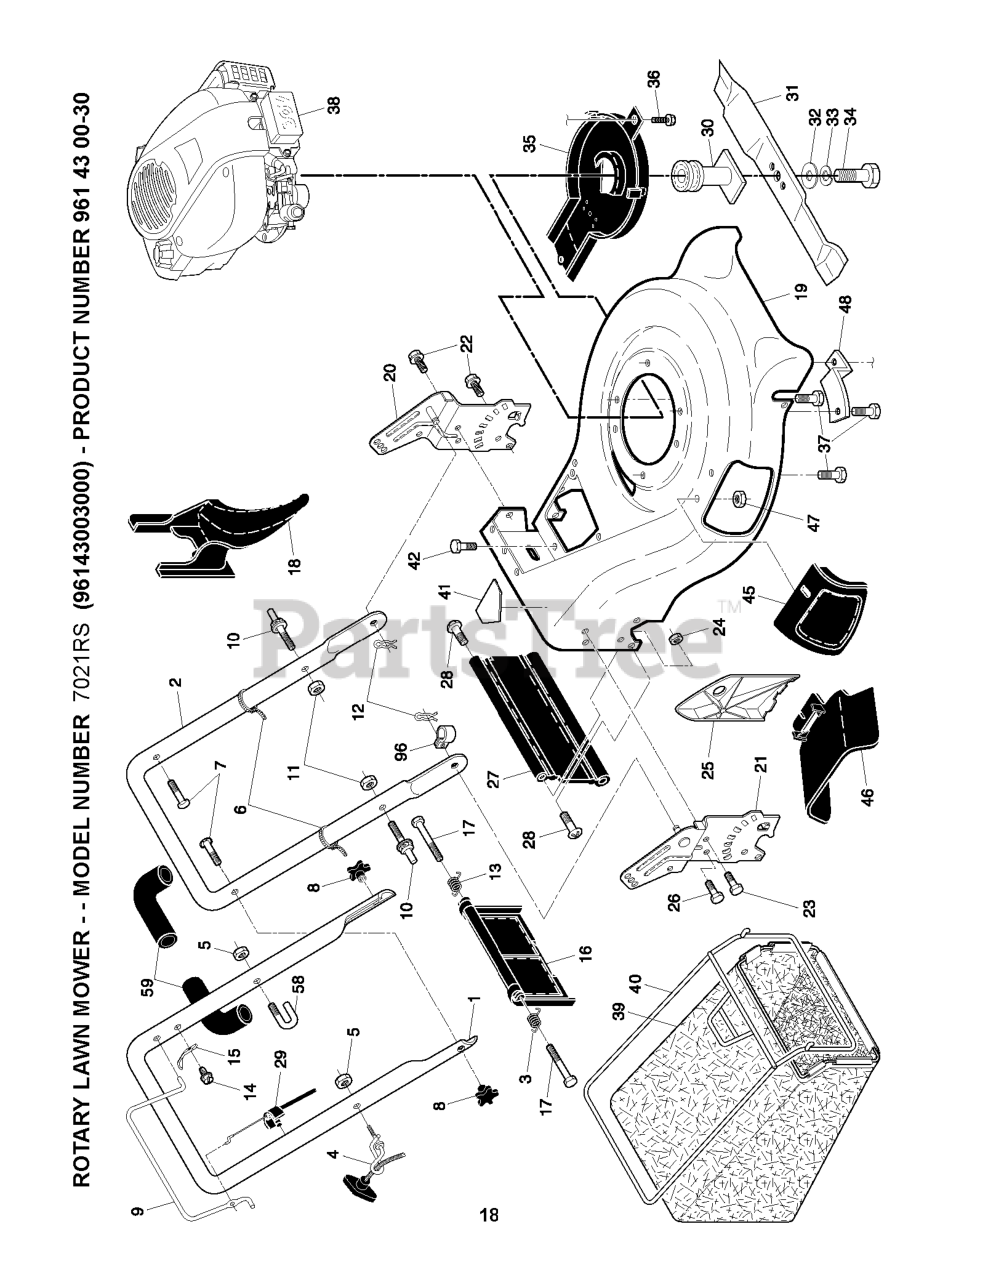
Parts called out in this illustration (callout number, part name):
1	HANDLE.ASM.UP.OFF/EZ.CR.W/GRIP
2	HANDLE.LOWER.21.GREY
3	SPRING.RH.REAR.DOOR.21.RWGD
4	RB GUIDE.ROPE.STD.BLK.ZIN WSL
5	NUT
6	TIE GUIDE
7	BOLT, HANDLE 5/16-18X1.75
8	KNOB.HANDLE.STAR.HUSQ.GRAY
9	BAIL.DSTRT.FL.AW.CREAS.ORANGE
11	NUT.LOCK.5/16-18
12	HAIRPIN COTTER
13	SPRING.LH.REAR.DOOR.21.RWGD
15	BRACKET UPSTOP
16	REAR DOOR ASSEMBLY
18	PLUG.MULCHER.RGD.21.
19	HOUSING.21.RWD.MC.ORANGE.WALK
20	BRACKET.HNDL.ASM.21.RWGD.LT.OR
21	BRACKET.HNDL.ASM.21.RWGD.RT.OR
22	SELF-TAPPING SCREW 5/16-18X3/4
23	BOLT, HEX HEAD 5/16-18
24	NUT.71038.31-18.HEX.NYLOCK
25	CLIPPING DEFLECTOR
27	SKIRT.REAR.21.RWGD.BLACK(2 2M)
28	HINGE SCREW
29	RP CABLE
30	BLADE ADAPTOR / PULLEY
31	BLADE.21.PUSH/RWGD/FWGD
32	WASHER,HARDEN
33	LOCKWASHER
34	SCREW, HEX HD 3/8-24 X 1-3/8
35	DEBRIS SHIELD
36	SCREW.HEX.WSH
37	BOLT 3/8-16X1-1/8
39	GRASSBAG
40	FRAME.GBAG.21.RWGD.SC
41	DANGER DECAL
45	MULCHER DOOR ASM.
46	DEFLECTOR
48	BRACKET
59	GRIP.HANDLE.FOAM.WIDE.(1 SIDE)
96	CLIP.CABLE.BLK
